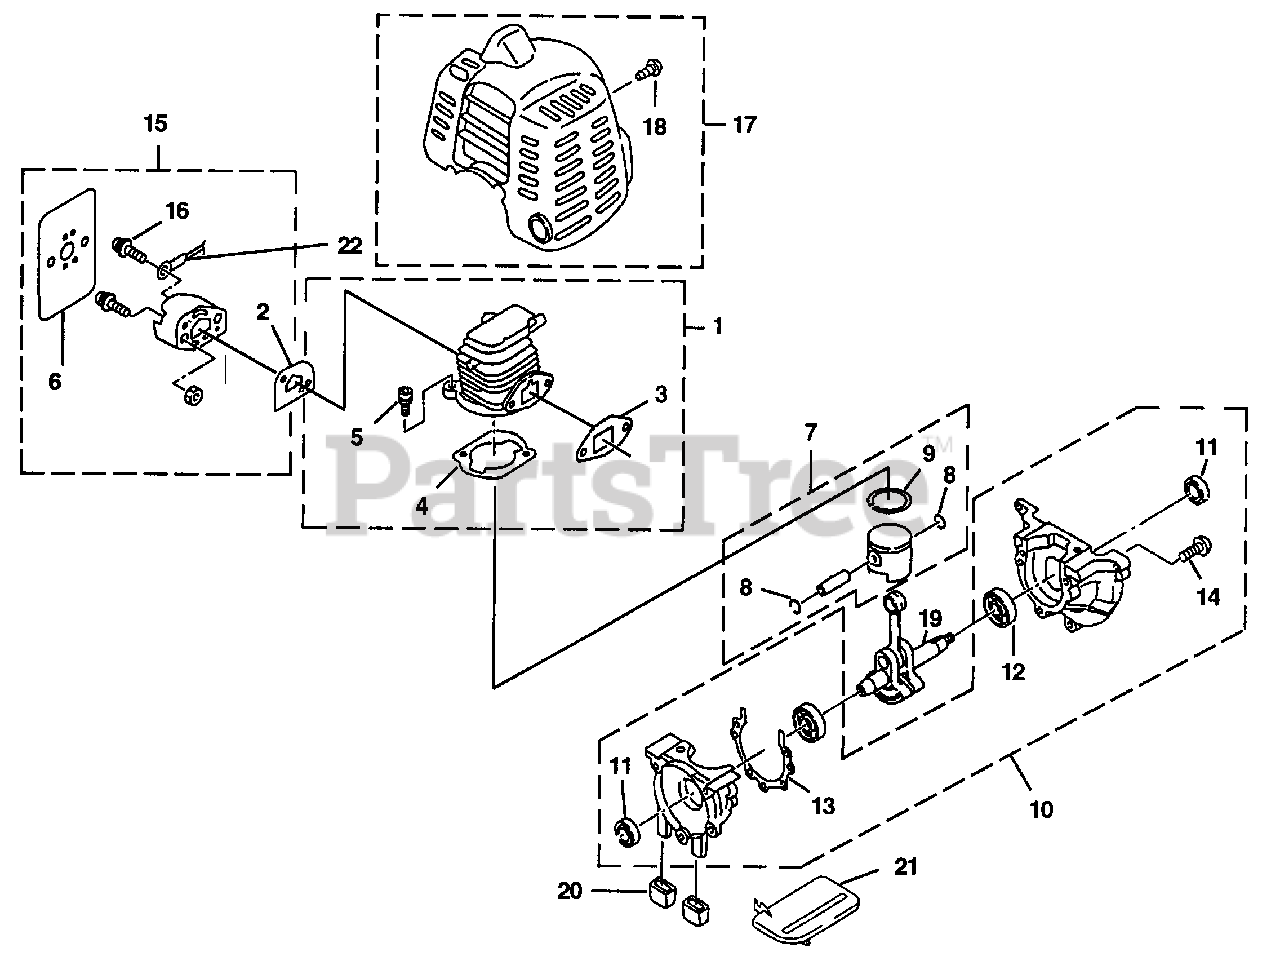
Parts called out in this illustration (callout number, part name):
1	CYLINDER ASSEMBLY
2	GASKET-Heat Dam
3	GASKET-Muffler
4	GASKET-Cylinder
5	SCREW-Socket HD (M5 x 20 SW)
6	GASKET-Carburetor
7	PISTON ASSEMBLY
8	RING-Retaining
9	RING-Piston
10	CRANKCASE ASSEMBLY
11	OIL SEAL
12	BALL BEARING
13	GASKET-Crankcase
14	SCREW (M5 X 25)
15	HEAT DAM ASSEMBLY W/Nuts
16	SCREW ASSEMBLY (M5 x 20)
17	CYLINDER COVER
18	SCREW-Self Tapping (M5 x 14)
19	CRANKSHAFT
20	RUBBER BUMPER KIT
21	MUFFLER PLATE
